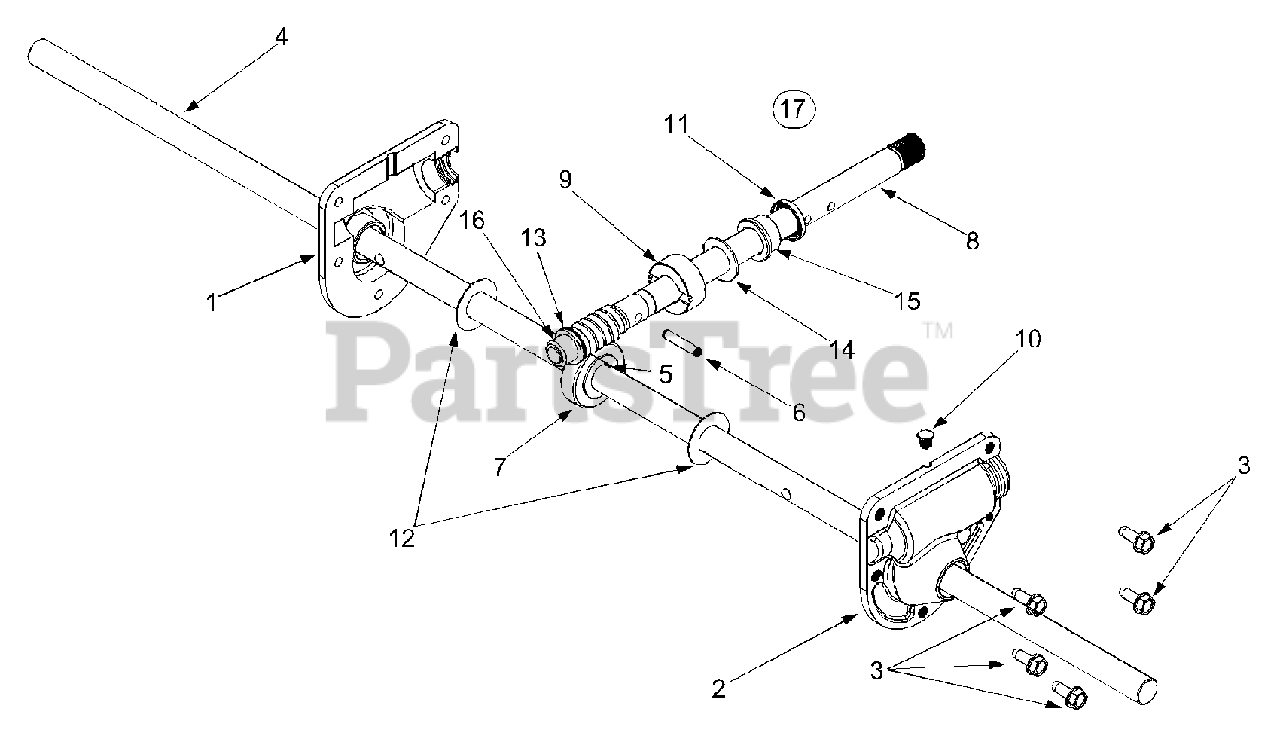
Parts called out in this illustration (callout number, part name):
1	Housing-R.H.
2	Hex Screw 1/4-20 x .75
3	Spiral Axle 22"
4	Key
5	Pin-Spiral
6	Shaft-Worm
7	Gear-Worm
8	Collar-Thrust
10	Seal-Oil
11	Washer-Flat
12	Washer-Flat
13	Washer-Flat
14	Grease
15	Bearing-Flange
16	Bearing-Flange
17	Ass'y. Complete 22"
